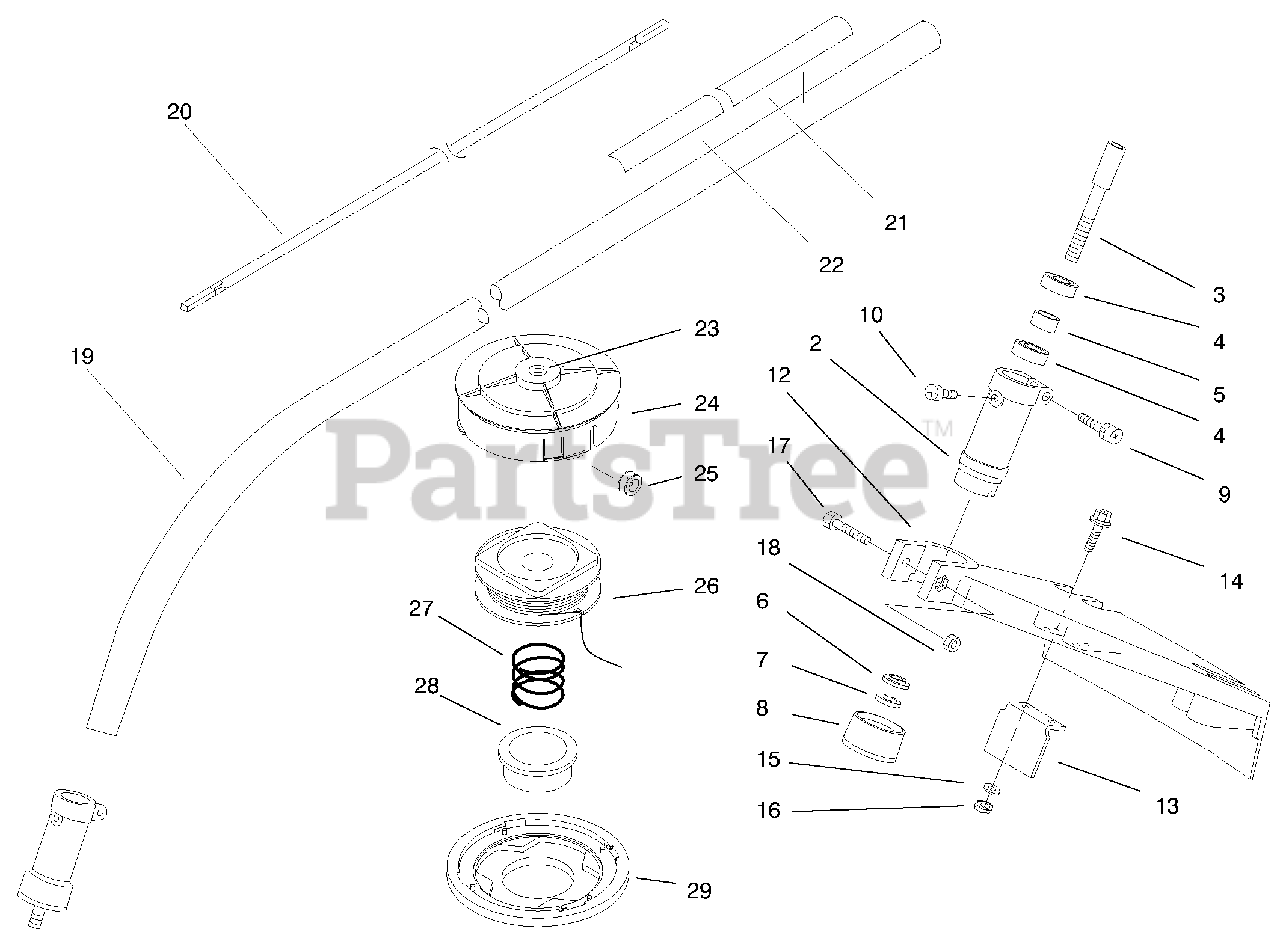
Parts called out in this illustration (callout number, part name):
2	Case-Bearing
3	Shaft-Attaching
5	Spacer-Bearing
7	Washer-Spring
8	Adapter-Attaching Shaft
13	Cutter-String
15	Washer-Spring
19	Driveshaft Tube Asm (Incl. Ref. # 22)
20	Driveshaft
21	Decal-Toro
22	Decal-Caution
26	Spool with Line
